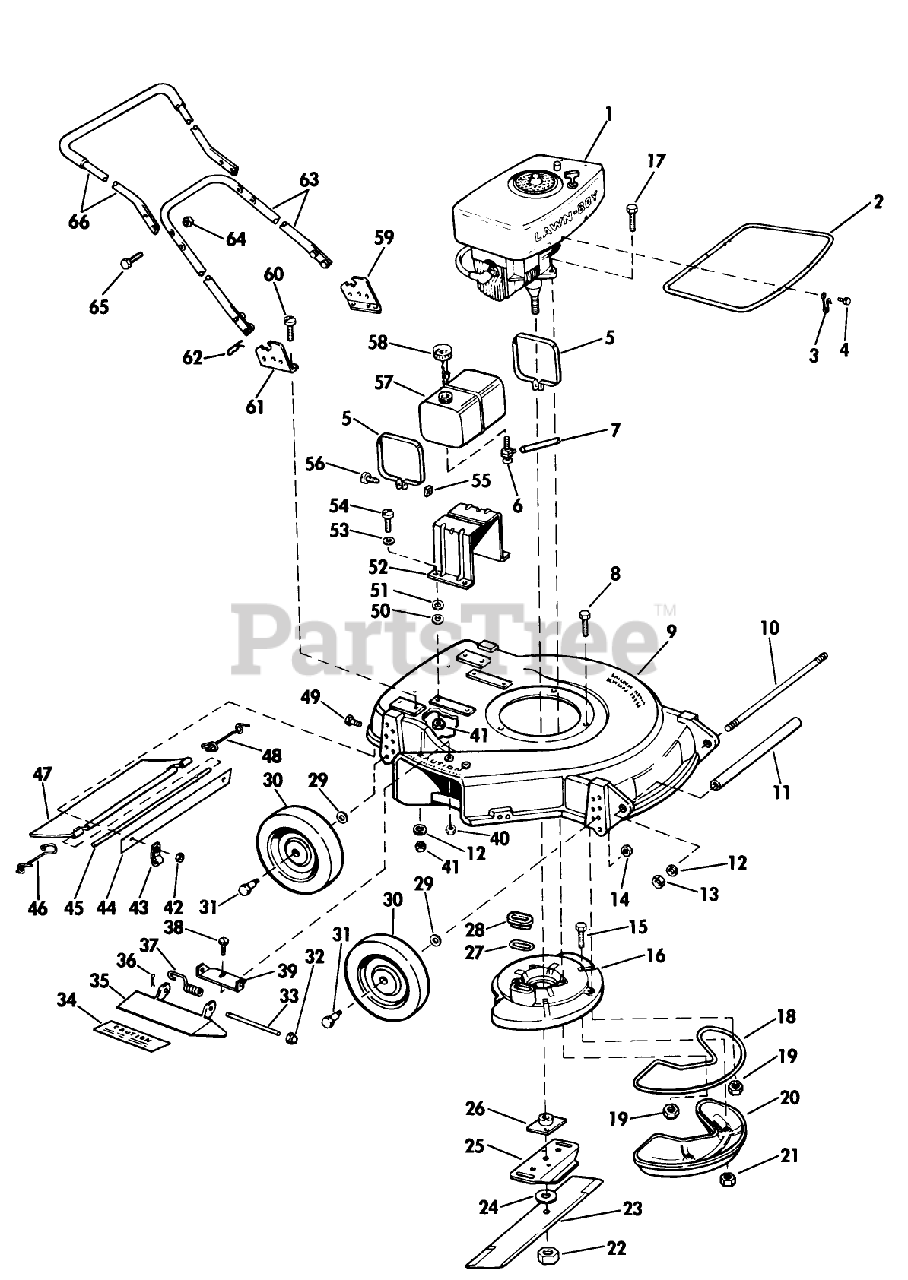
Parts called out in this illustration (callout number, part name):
6	VALVE&SCREEN SM
8	SCREW
12	WASHER WROUGHT
13	LOCKNUT
14	NUT
19	NUT-LOCK F
22	NUT-BLADE
24	WASHER
26	PLATE AND COLLAR ASM
27	GASKET S
28	SLEEVE
29	WASHER, LOCK
33	HINGE PIN
36	Cotter Pin
38	Screw
46	SPRING;TRAILING SHIELD RH
48	SPRIG T/SHLD ASOC
49	Screw
50	WASHER
54	BOLT PIONEER
55	Nut
60	SCREW S
65	SCREW
